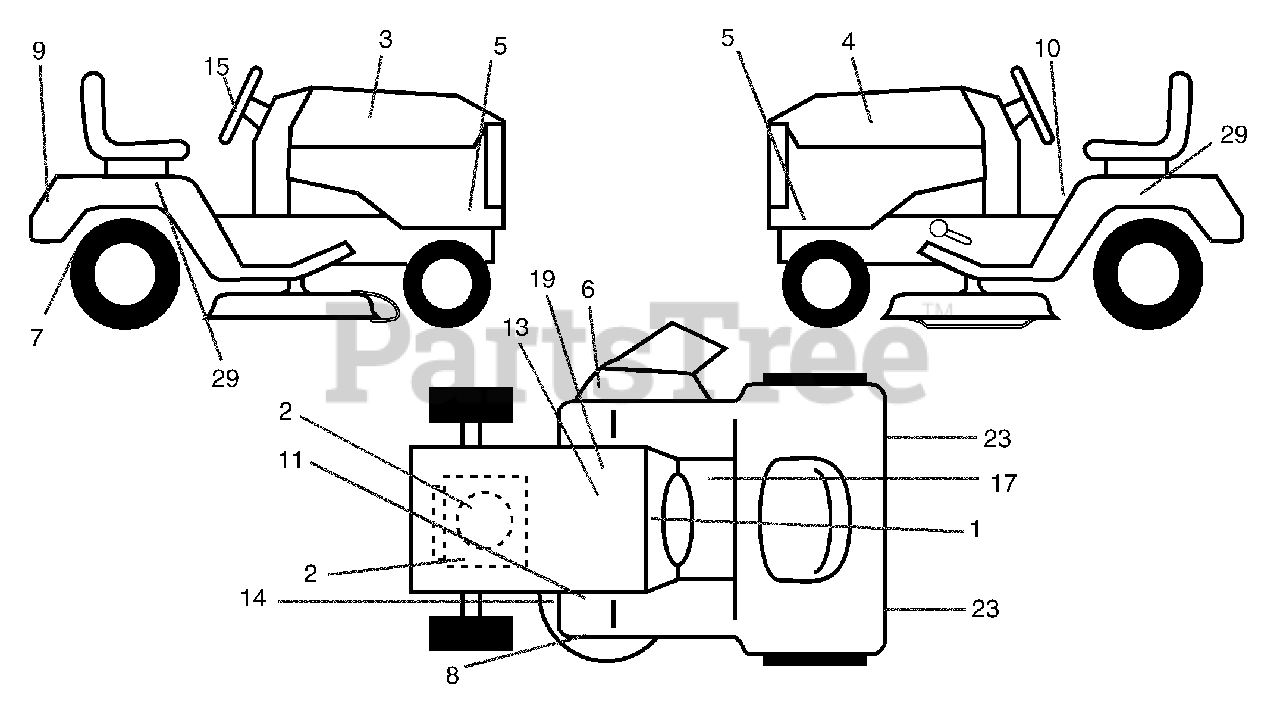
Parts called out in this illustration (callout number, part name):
1	Decal, Dash
2	Decal, Engine
3	Decal, Hood, RH
4	Decal, Hood, LH
5	Decal, Hood Sides
6	Decal, Warning
7	Decal, Bypass
8	Decal, Deck Caution
9	Decal
10	Decal, Danger
11	Ft. Rest
13	Decal, Battery
14	Decal, V-Belt Schematic
15	Decal, Ins. Whl. Strg.
17	Decal, Saddle Brake Parking
19	Decal, Battery
23	Reflector, Taillight
29	Decal, Fender Auto Trans
